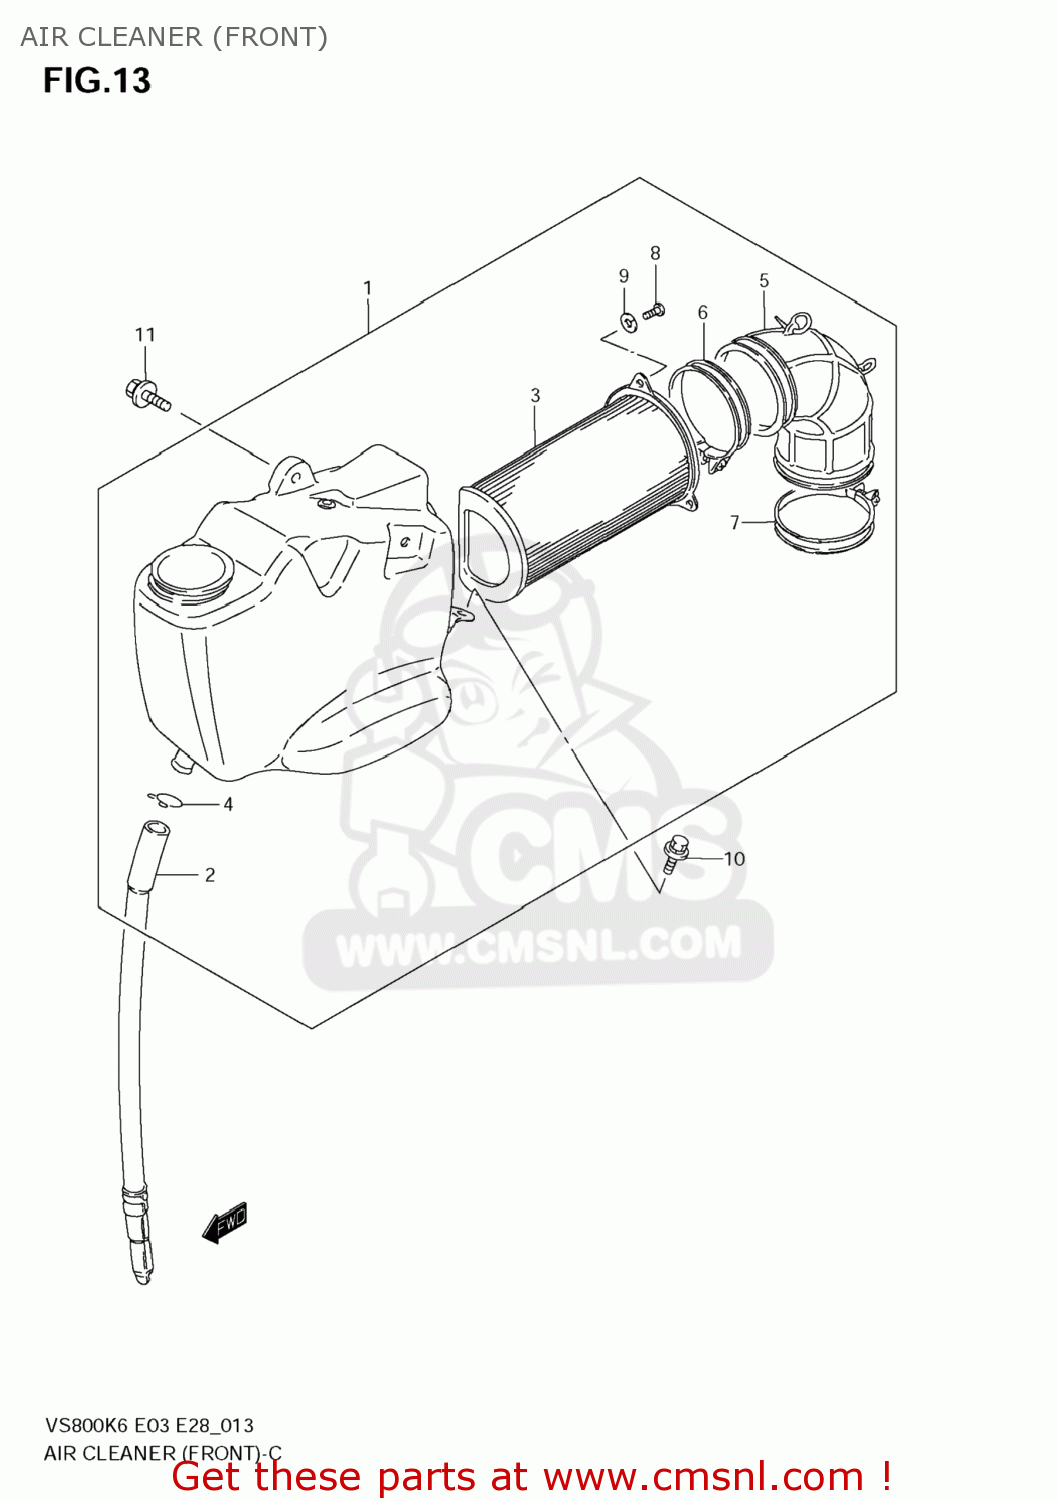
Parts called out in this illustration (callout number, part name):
1	CLEANER ASSY,AIR FR
2	TUBE,DRAIN
3	FILTER ASSY
4	CLIP
5	TUBE,AIR CLEANER OUTLET
6	CLAMP
7	CLAMP
8	SCREW
9	WASHER,LOCK
10	BOLT
11	BOLT
